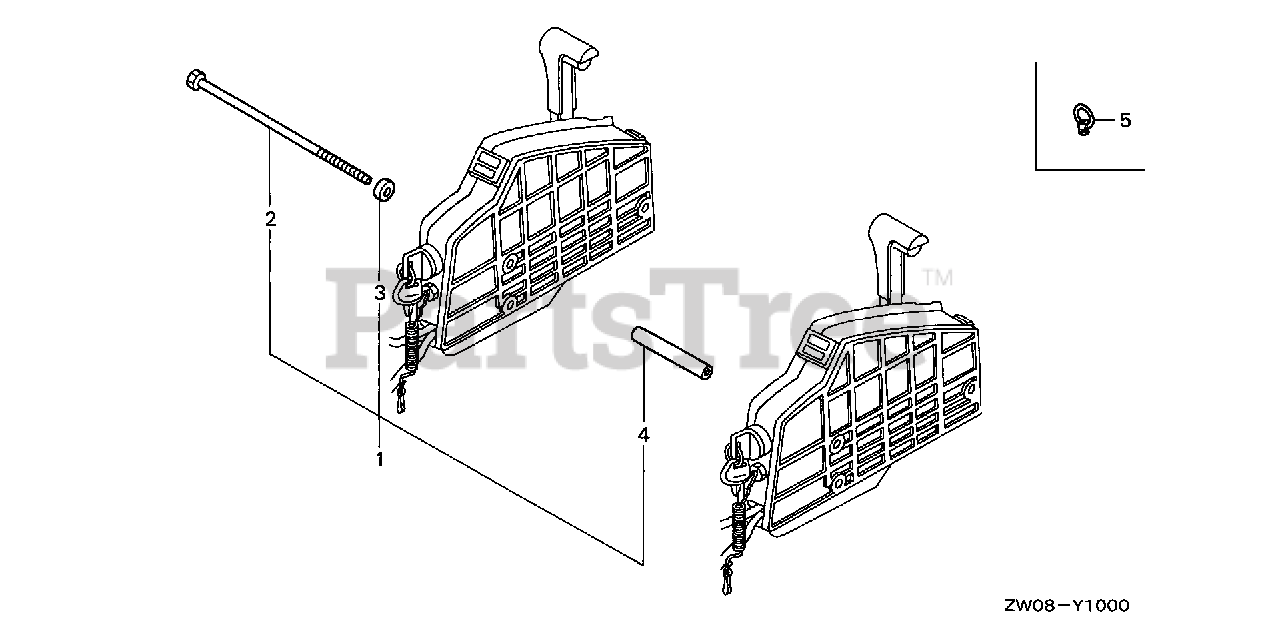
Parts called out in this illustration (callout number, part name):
1	BOLT KIT, SIDE REMOTE CONTROL
2	BOLT, SPECIAL (6X220)
3	COLLAR, DISTANCE (A)
4	COLLAR, DISTANCE (B)
5	EYE, LIFTING
